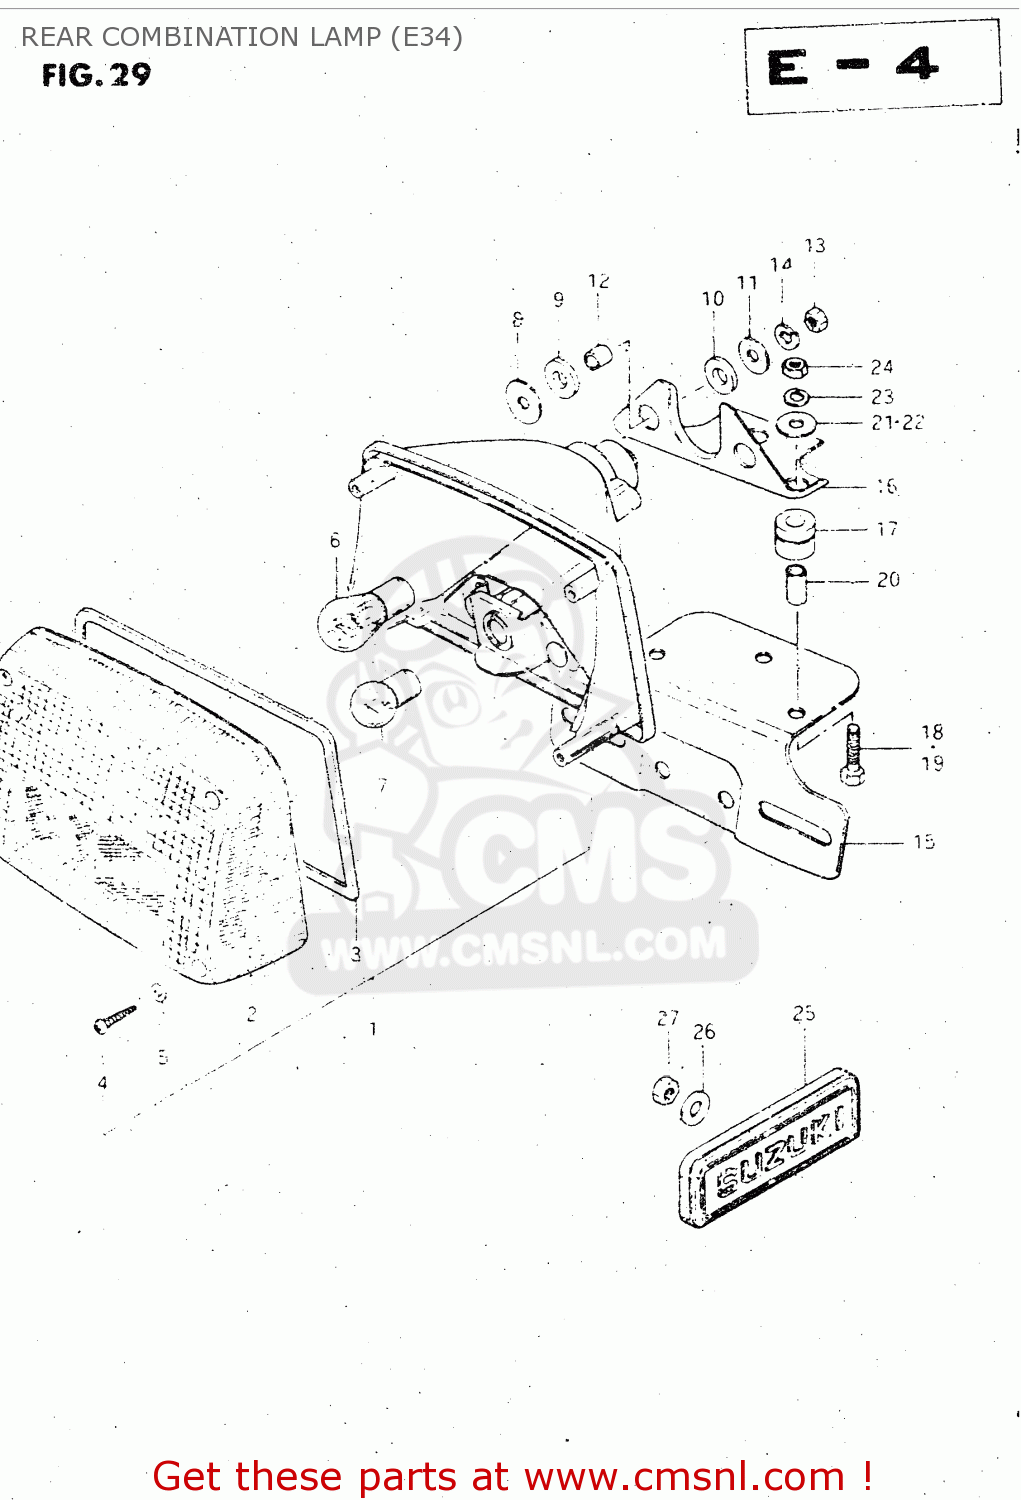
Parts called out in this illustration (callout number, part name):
1	LAMP, REAR COMBINATION
2	LENS
3	GASKET (NAS)
4	SCREW
5	GASKET (NAS)
6	BULB(12V21/5W)
7	BULB(12V10W,TOKAI DENSO)
8	WASHER
9	CUSHION
10	CUSHION
11	WASHER(6,5X22X1.6)
12	SPACER(6.1X9X7.5)
13	NUT
14	LOCK WASHER
15	BRACKET, LICENCE PLATE
16	BRACKET,LICENSE PLATE
17	CUSHION, BRACKET
18	BOLT
19	BOLT
20	SPACER (6.4X9X15.5)
21	WASHER
22	WASHER
23	LOCK WASHER
24	NUT
25	EMBLEM, REAR SIDE
26	WASHER
27	NUT
